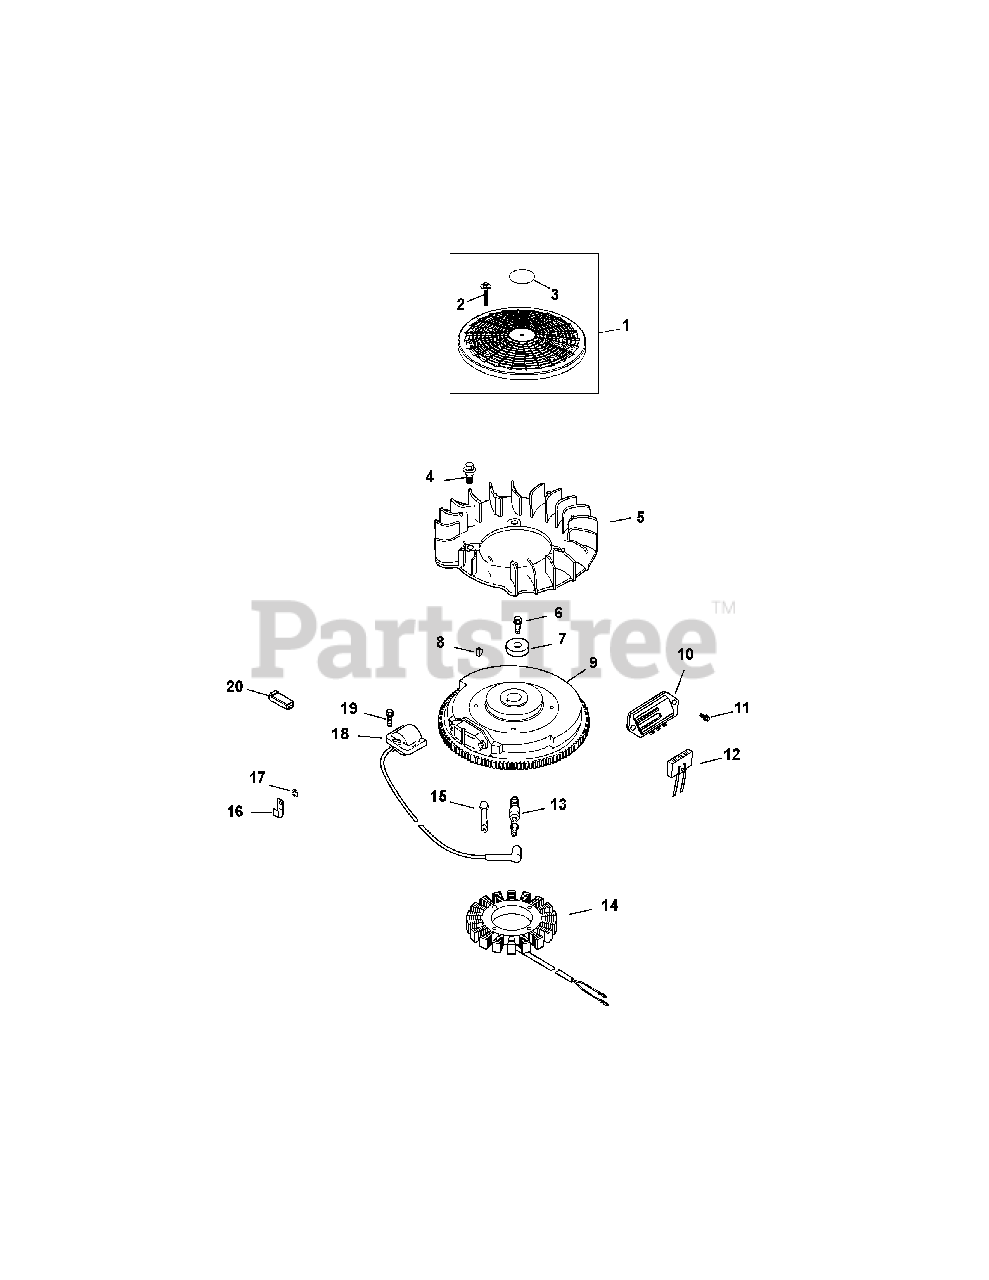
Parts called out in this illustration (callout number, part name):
1	KIT, GRASS SCREEN (includes 2,3 )
2	SCREW, FLG SEMS M4X.7X25
3	DECAL, GRASS SCREEN
4	BOLT, SHOULDER
6	SCREW, FLG M10X1.5X45
7	WASHER, FLAT 13/32''
8	KEY, 3/16'' X 5/8''
10	REGULATOR/RECTIFIER
11	SCREW, HEX FLANGE HI-LO
13	PLUG, SPARK (STD)
14	KIT, 15 / 20 AMP STATOR
15	SCREW, THD FRM M5X0.8X25
16	CLIP, CABLE
17	WASHER, FLAT 1/4'' (O.D. 1/2'')
18	KIT, MODULE IGNTN (CDI FIXED)
19	SCREW, FLG THD FRM M5X.8X20
20	CONNECTOR (1 CONTACT)
